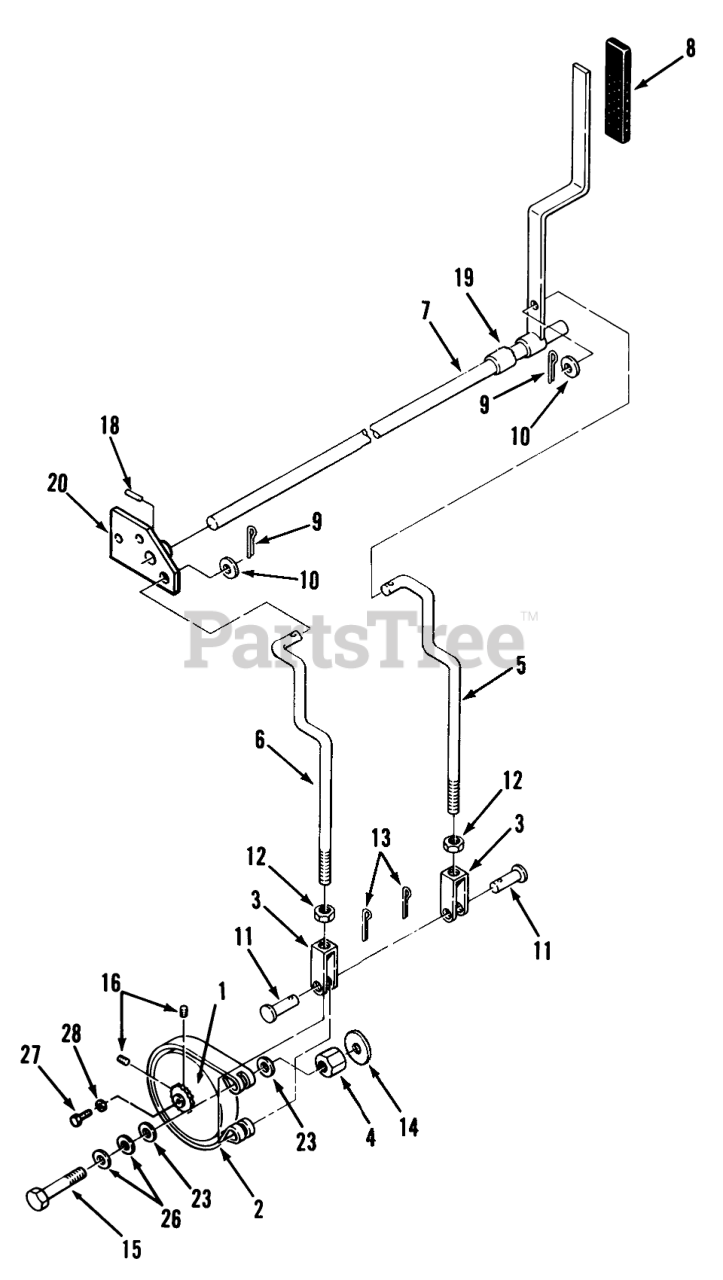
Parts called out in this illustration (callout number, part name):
1	ASS'Y-DRUM SPROCKET
2	BRAKE-BAND
3	ASSY-YOKE BRAKE
4	NUT-COUPLING
5	ROD-BRAKE L.H.
6	ROD-BRAKE R.H.
7	ASSY-PARKING BRK
8	GRIP BRAKE20258-K
9	Cotter Pin
10	WASHER 5/16 SAE
11	Clevis Pin 5/16 x 1 1/4
12	Nut-Lock
13	Cotter Pin
14	WASHER
15	Bolt
18	Roll Pin
19	SPACER-PARKING BR B
20	Parking Brake Lever
23	Washer
26	WASHER-SPRING
27	H H C S
28	WASHER
